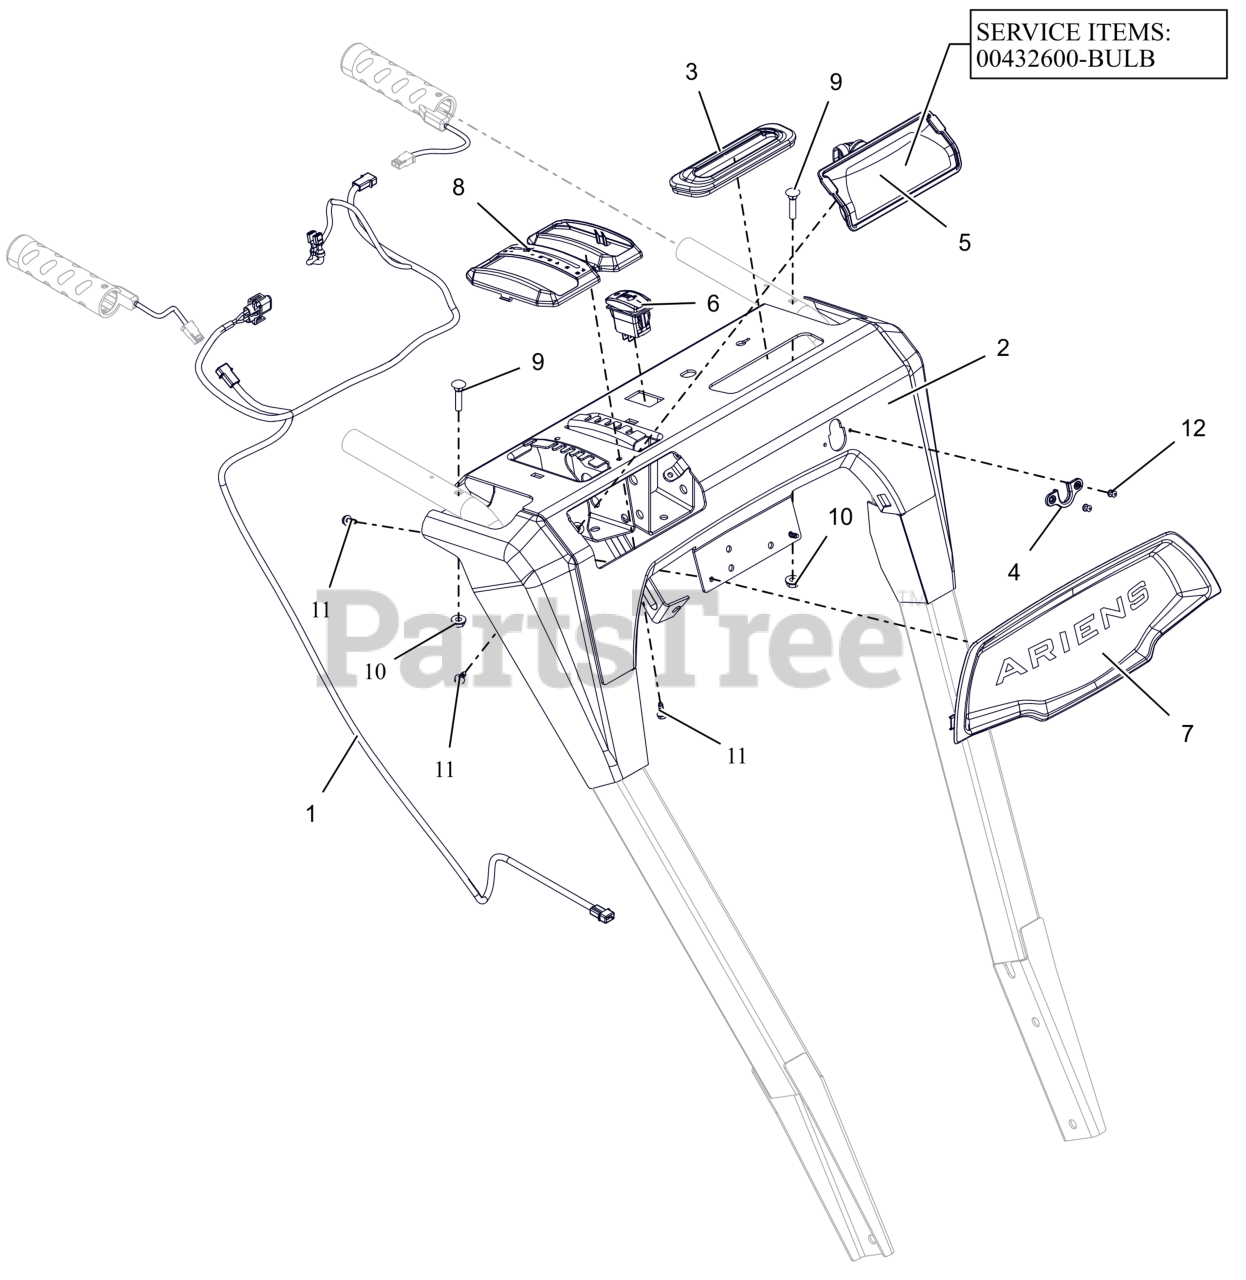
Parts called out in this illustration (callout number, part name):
1	HARNESS, LIGHT & WARMER
2	PANEL, DASH-FRICTION W/DECAL
3	GROMMET, BOOT, QUICK TURN
4	GROMMET, CABLE, QUICK TURN 2
5	HEADLIGHT ASY, HALO 20W 2SHOT
5	BULB, LIGHT-HALOGEN 20W
6	SWITCH,ROCKER SPST-ON/OFF
7	BEZEL, DASH - ARIENS LG DASH
8	BEZEL, SHIFT - FRICTION SNOW
9	BLT-RDHDXLSQNK.25-20X1.25 G5ZC
10	NUT-LK-CTR-FLG .25-20 ZC120
11	SCR, PLASTIC #10X.50
12	RVT-POP #43 .125X.313 STL ZINC
